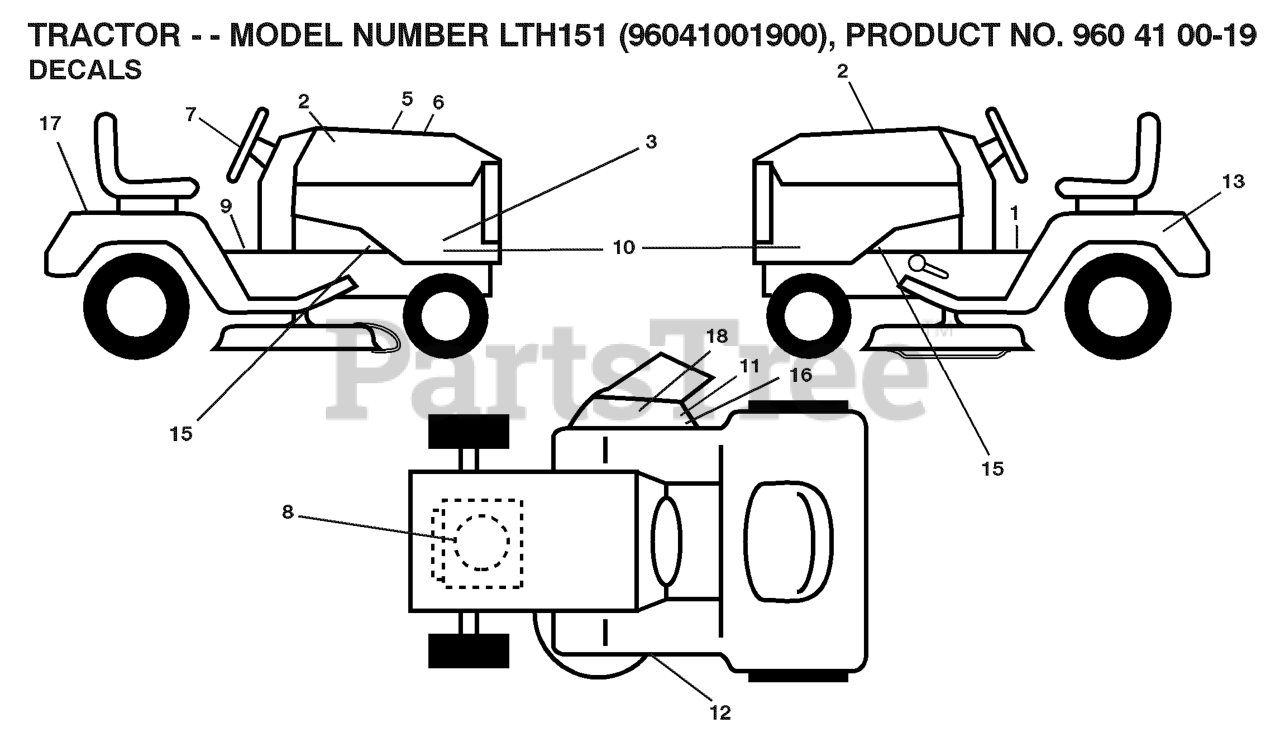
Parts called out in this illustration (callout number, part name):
1	LABEL
2	DECAL.HOOD.NAMELOGO.HUSQ
7	DECAL.WHEEL.STRG.LGN.H
8	DECAL
9	DECAL BTRY SYMBOLS
10	DECAL SIDE PANEL
11	DECAL.INTERNATIONL.CUTFINGER
12	DECAL.V-BELT.SCHEMATIC.36/38/9
13	Decal, Fender 100 DB/CE
15	DECAL
16	DECAL PARK BRAKE
17	DECAL, DEFLECT WARNING
18	Decal, Fender 100 DB/CE
